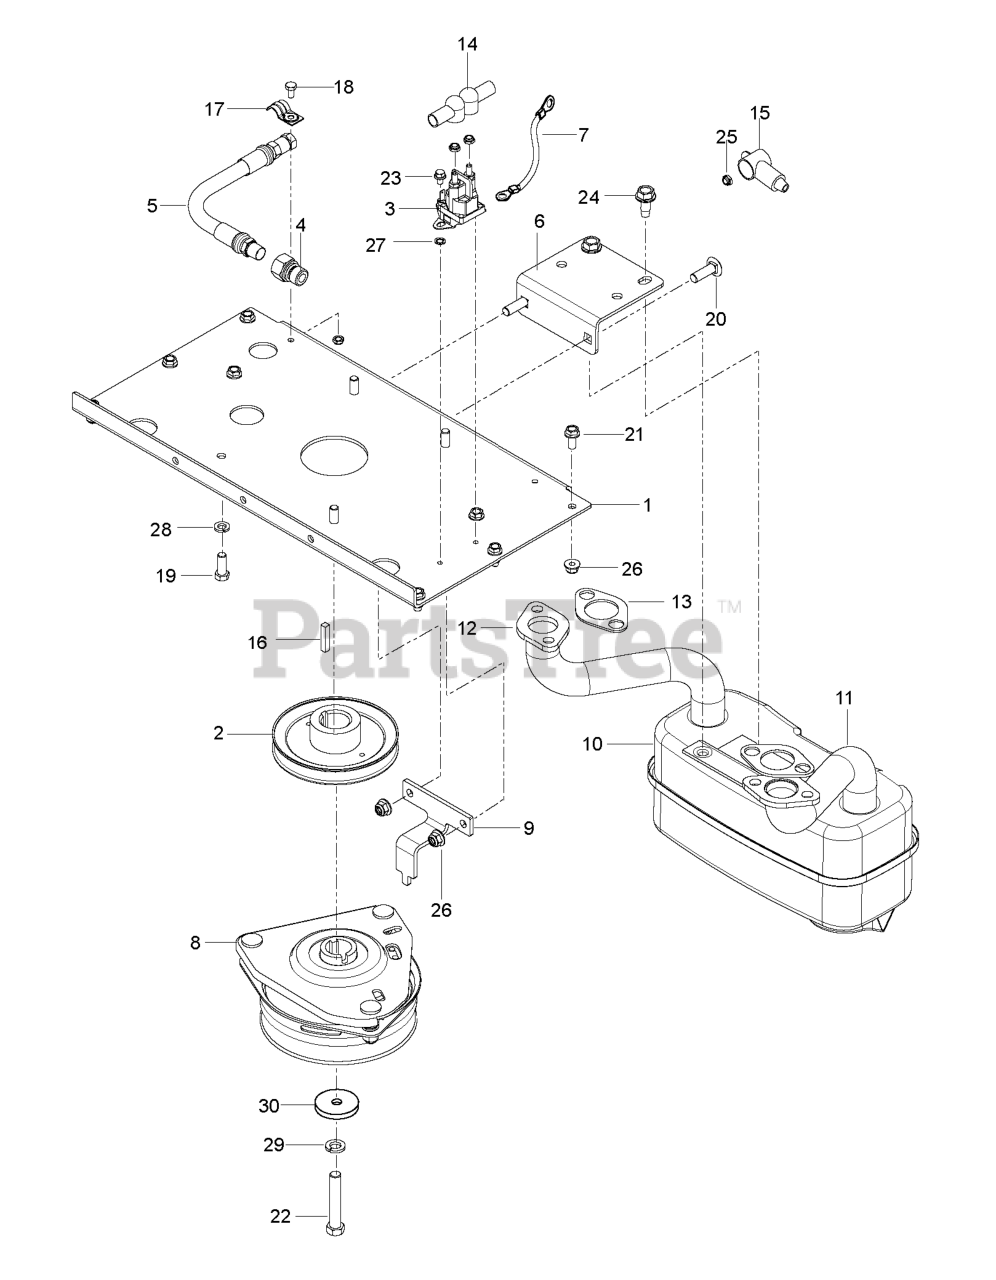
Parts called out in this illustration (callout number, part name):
1	PLATE.PNT.ENGINE.E-DIP
2	PULLEY.DRIVE.XMSN
3	SOLENOID.STARTER.BRASS.PLUNGER
3	Solenoids
4	ADAPTER, OIL DRAIN
5	HOSE.ASSEMBLY.OIL.DRAIN
6	BRKT, MUFFLER, BLK
7	CABLE POSITIVE
8	CLUTCH MZ ZTR GT.48/54"1.125"
9	BRACKET.CLUTCH.STOP.PNTX431
10	MUFFLER ASM TWIN
11	TUBE.EXHAUST.LH.FR961/FR730
11	PIPE.EXHAUST.LH.CV18/20
12	TUBE.EXHAUST.RH.FR961/FR730
12	PIPE.EXHAUST.RH.CV18/20
13	GASKET.EXHAUST.KAWASAKI
14	TERMINAL COVER
16	KEY, 1/4 SQ X 1 1/4
18	Screws
18	HCS 1/4-20.
19	Bolts
19	HCS 3/8-16X1.GRD.5.ZD
19	SCREW 3/8-16X1
20	RHSSNB 5/16C X 1.0
20	Bolts
21	HHFS 5/16-18 X 3/4
21	Bolts
22	CLUTCH BOLT7/16-20X2.5 GR596HR
23	HWST 1/4C X 3/8
24	Bolts
24	SCREW.THDROL.5/16-18X3/4.TTY
24	BOLT 5/16-18 X 3/4
25	JAM NUT 1/4C (2 2 PW01)
25	Hardware
26	NUT HEXAGON FLANGE 5/16-18 ST
26	5/16-18 NYLOC FLANGE NUT
27	WASHER 1/4 INT TOOTH
27	NUT HEXAGON FLANGE 5/16-18 ST
28	SLW 3/8 STD
28	Washers
29	WASHER 7/16 LOCK
29	Washers
30	SPINDLE WASHER
